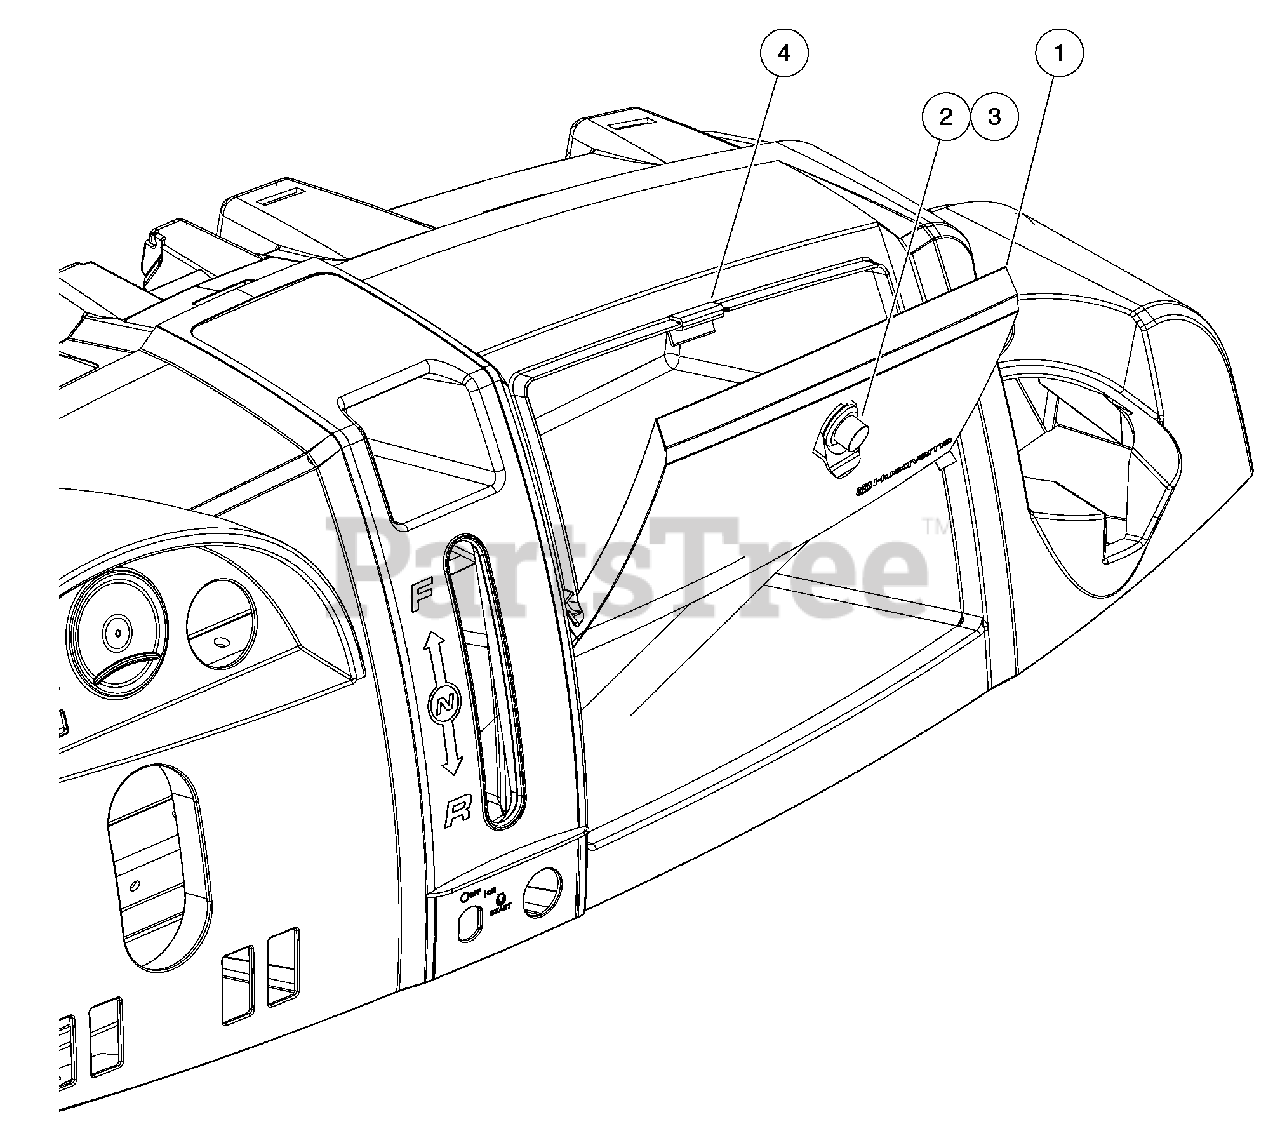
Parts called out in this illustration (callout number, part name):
1	Cover, Storage, Dash, Awd, Cci
2	Latch, Push Close
3	Latch, Push Close W/ Key
4	Keeper, Latch, Push Close
